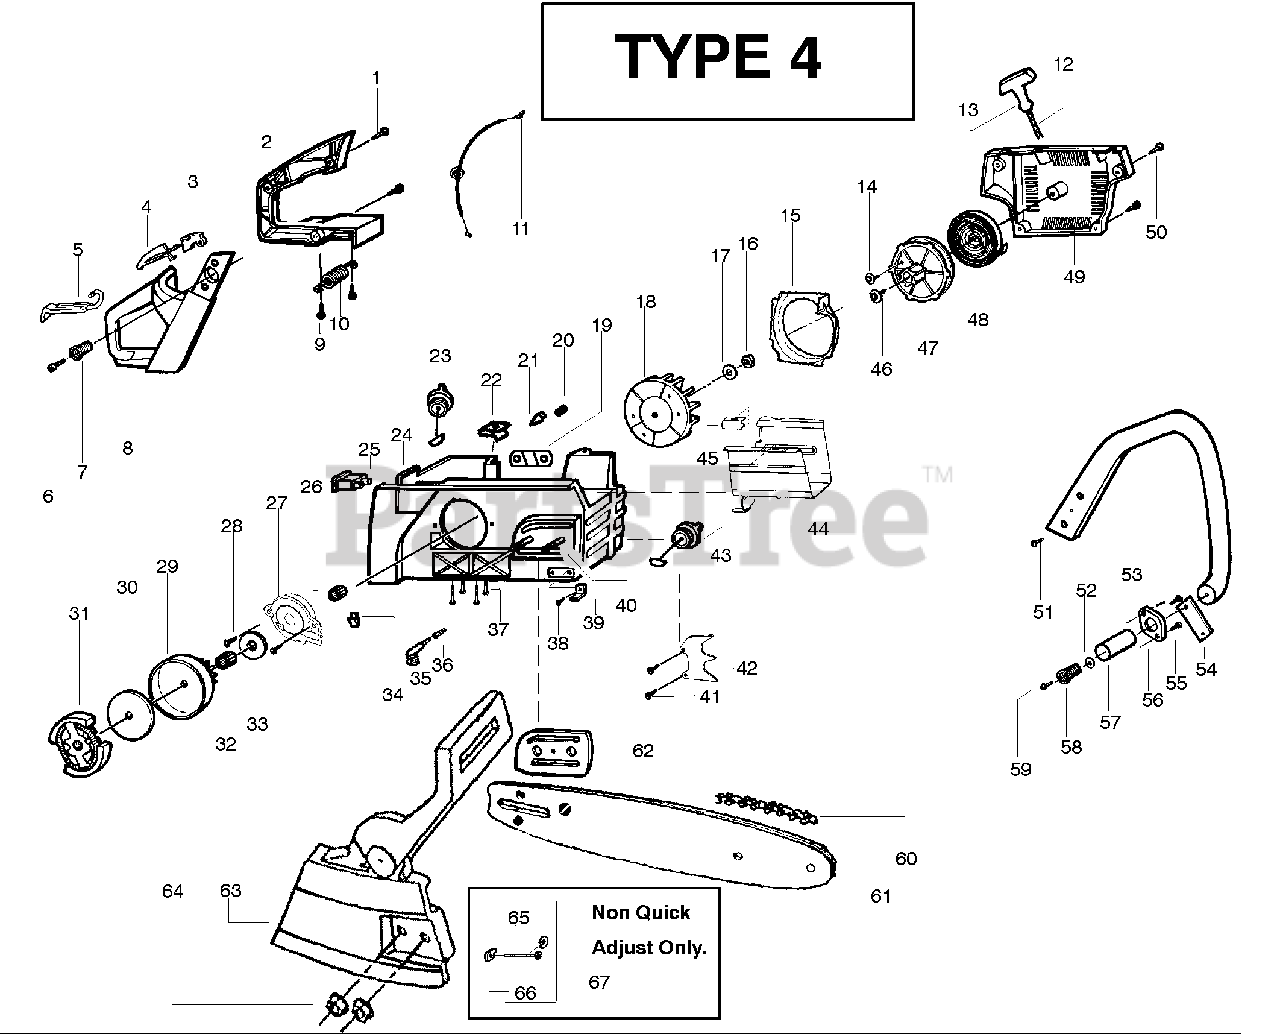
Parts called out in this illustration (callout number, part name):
3	Trigger-Throttle
4	Lockout-Throttle
7	Spring-Isolator
10	Spring-Isolator
11	Assy-Throttle Cable
13	Handle-Starter
15	Plate-Baffle Fan
17	Washer-Flywheel
18	Assy-Flywheel
19	Plate-Support (Bar Stud)
23	Assy-Fuel Cap
26	Worm-Oil Pump
27	Assy-Oil Pump
29	Kit-Clutch Drum
30	Washer-Clutch
32	Bearing-Clutch
33	Washer-Thrust
34	Seal-Oil
39	Chain Catcher
42	Kit-Spike Assy
43	Assy-Oil Cap
47	Kit-Starter Pulley
48	Spring-Recoil
49	Housing-Fan
52	Washer
53	Handle-Front
54	Front Strap-AV
56	Plate-Isolator
57	Spring Sleeve-AV
58	Spring-Isolator
61	Bar 16" Standard
61	Bar 20" Quick Adjust
61	Bar 20" Pro Lam Quick Adj.
63	Assy-ChainBrake (w/Standard Bar)
63	Assy-ChainBrake (w/Quick Adjust Bar)
64	Nut-Bar Mounting
66	Pin-Bar Adjust
67	Kit-Bar Adjust
